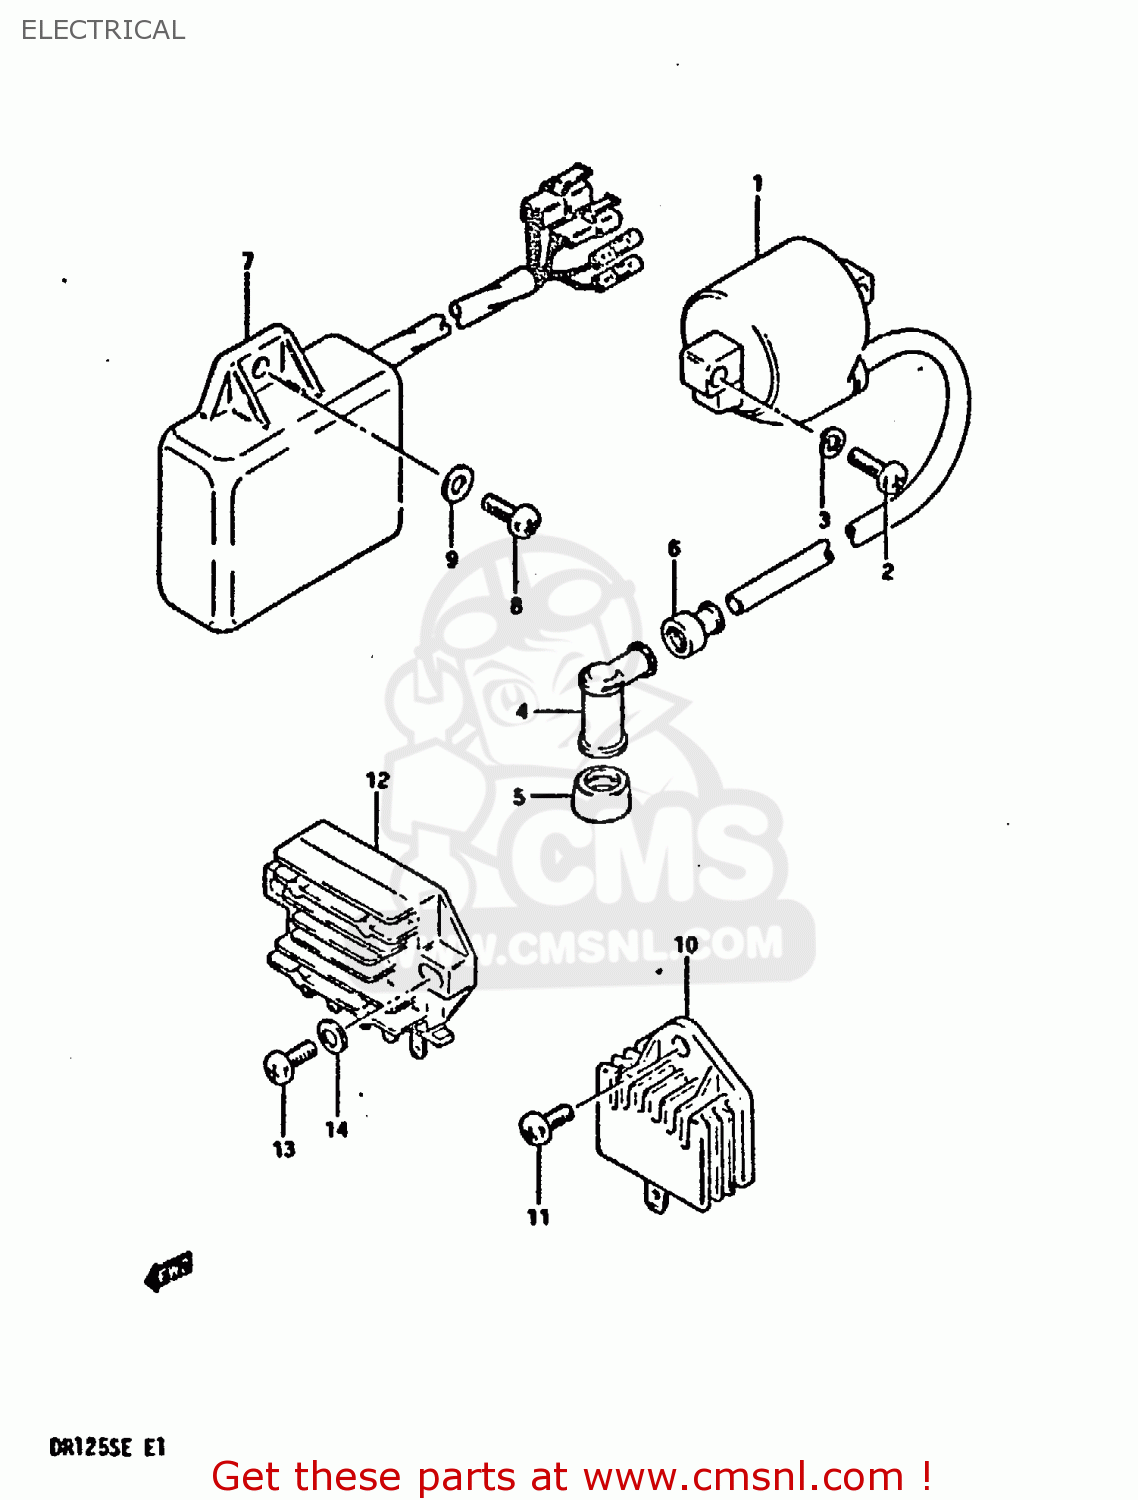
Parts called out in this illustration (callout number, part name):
1	COIL ASSEMBLY,IGNITION
2	SCREW
3	LOCK WASHER
4	CAP ASSY,SPARK PLUG
5	SEAL,SPARK PLUG
6	SEAL,SPARK PLU
7	CDI UNIT
8	SCREW
9	WASHER
10	RECTIFIER ASSY,REGULATOR
11	SCREW 6X12
12	RECTIFIER ASSEMBLY
13	SCREW
14	WASHER
